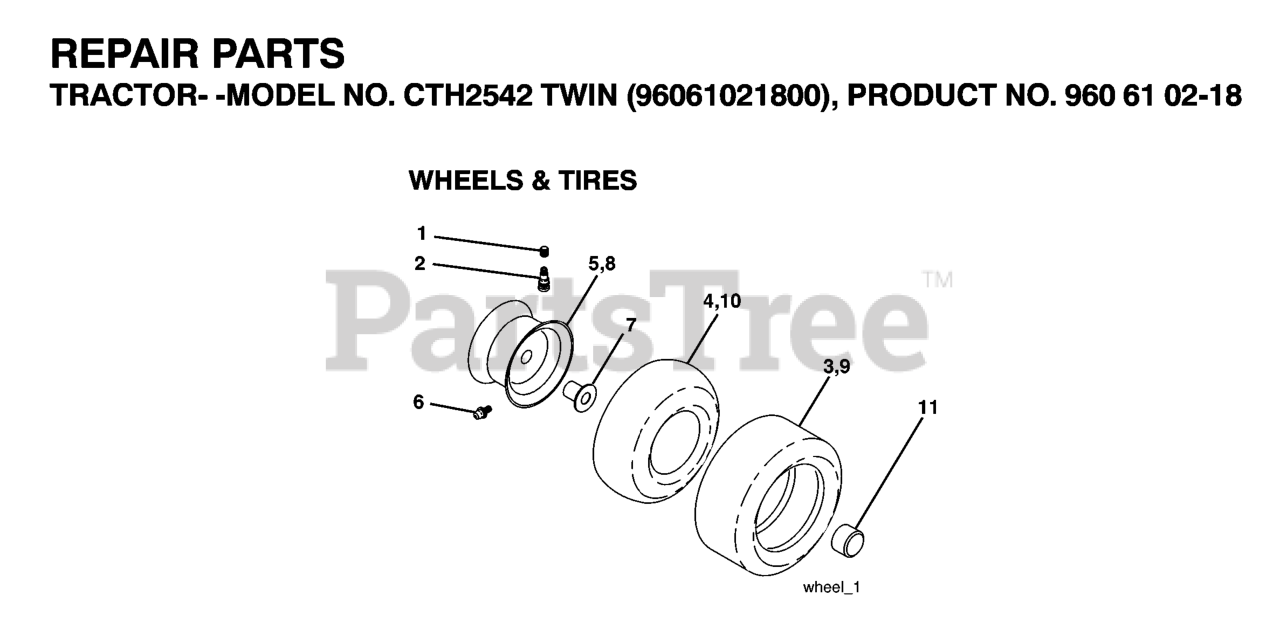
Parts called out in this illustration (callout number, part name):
2	VALVE STEM LT
3	TIRE HEAVY DUTY
4	TUBE.5.3/4.5/6
5	RIM ASM 6" FRONT SILVER
6	FITTING LT
7	BEARING T
8	RIM ASM 8" REAR SILVER
9	TIRE.TS.20X10-8
10	TUBE
11	CAP, AXLE BLK
